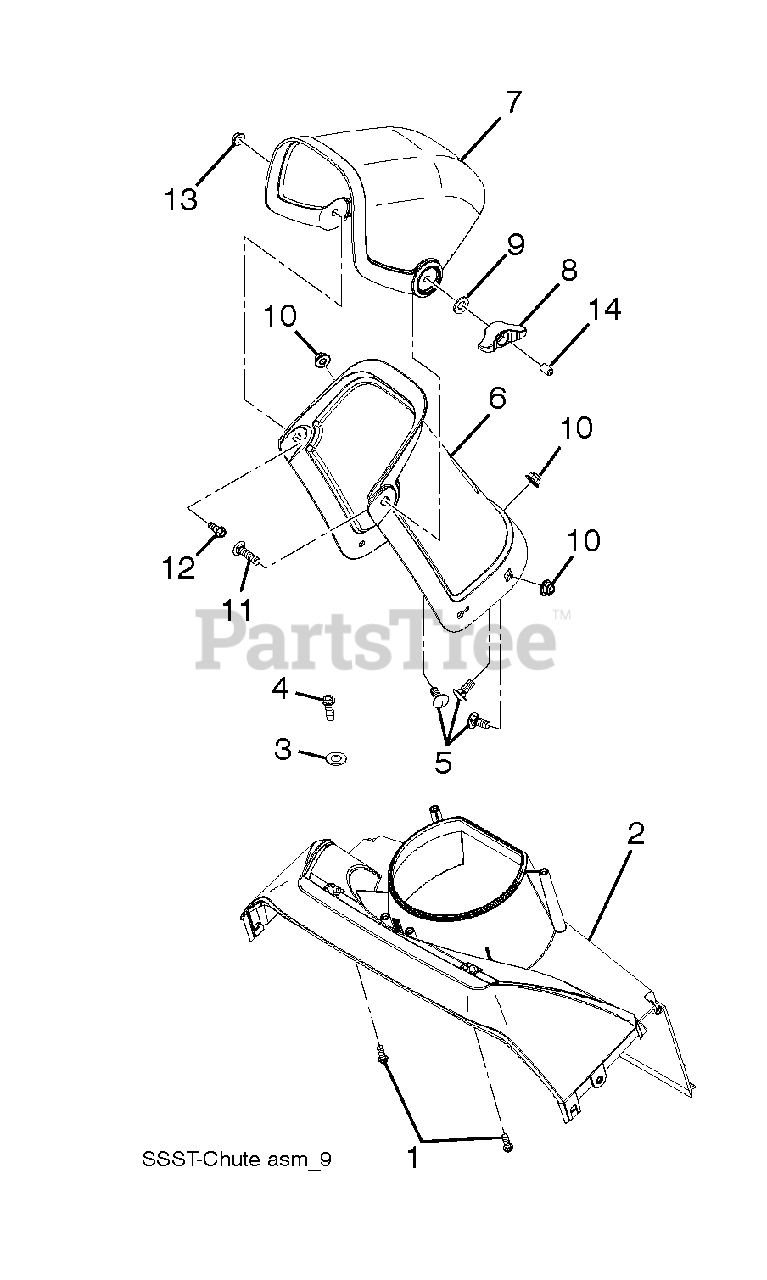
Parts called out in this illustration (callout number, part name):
1	SCREW.HX.13X.750
2	AUGER.PLENUM.SINGLE.STAGE.GREY
3	WASHER
4	BOLT.HEX.HD.WASHER.5/16-18X.75
5	BOLT.RH.SQNK.5/16
6	CHUTE.GREY.EURO
7	DEFLECTOR.SNOW.GREY
8	KNOB, DEFLECTOR
9	WASHER,HARDEN
10	LOCKNUT-FLANGE 5/16-18
11	BOLT.CARRIAGE.5/16-18
12	BOLT.SHOULDER.HEX.HD.1/4-20
14	PLUNGER CAP
